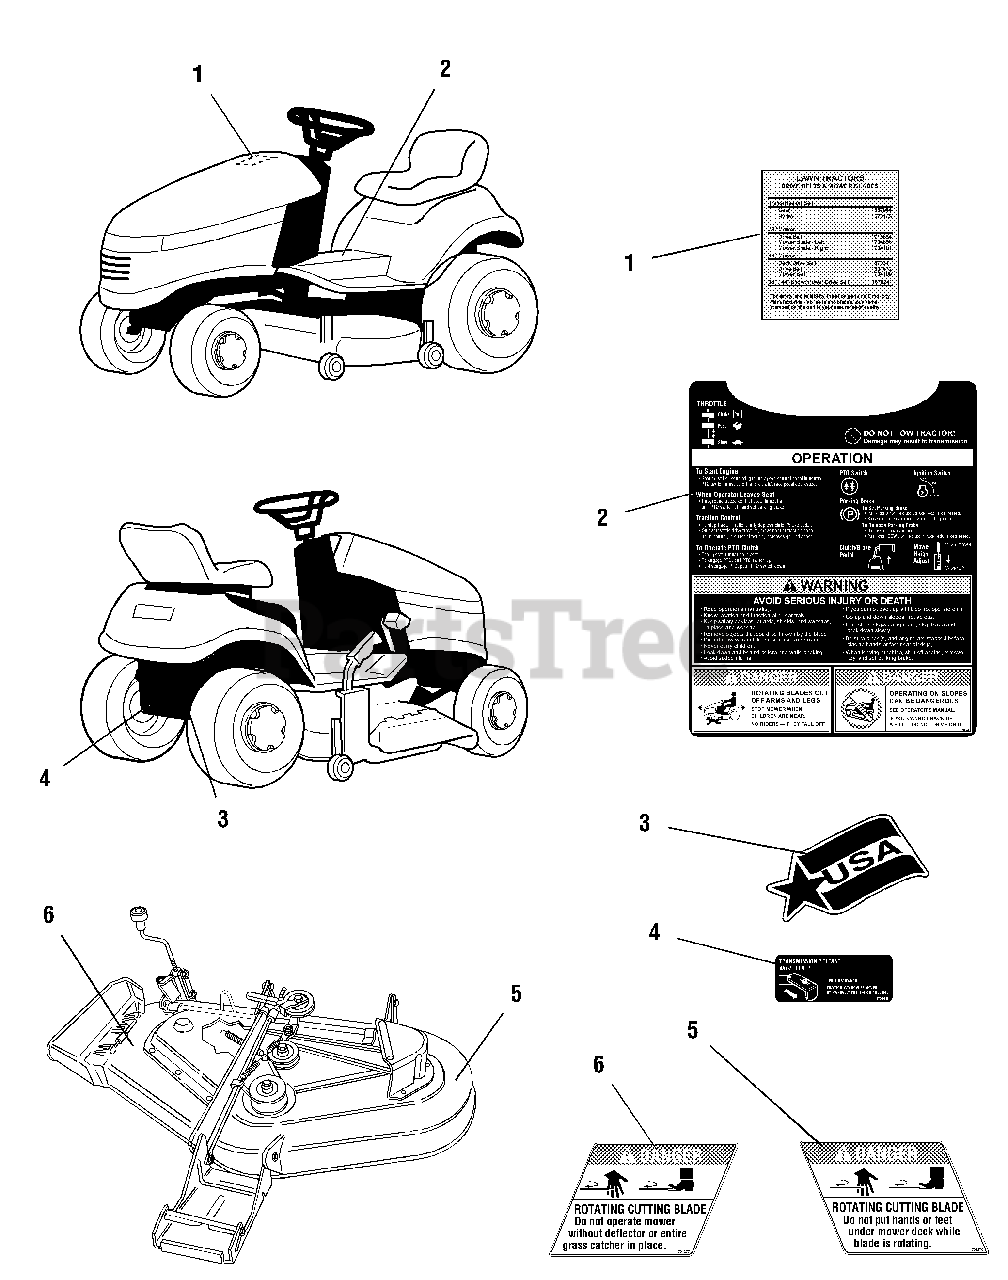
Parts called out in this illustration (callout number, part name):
1	DECAL, Belt/Blade
2	DECAL, Operating Instructions
3	DECAL, Logo, USA
4	DECAL, Release Valve
5	DECAL, Danger, Rotating Cutting Blade
6	DECAL, Danger, Chute in Place
